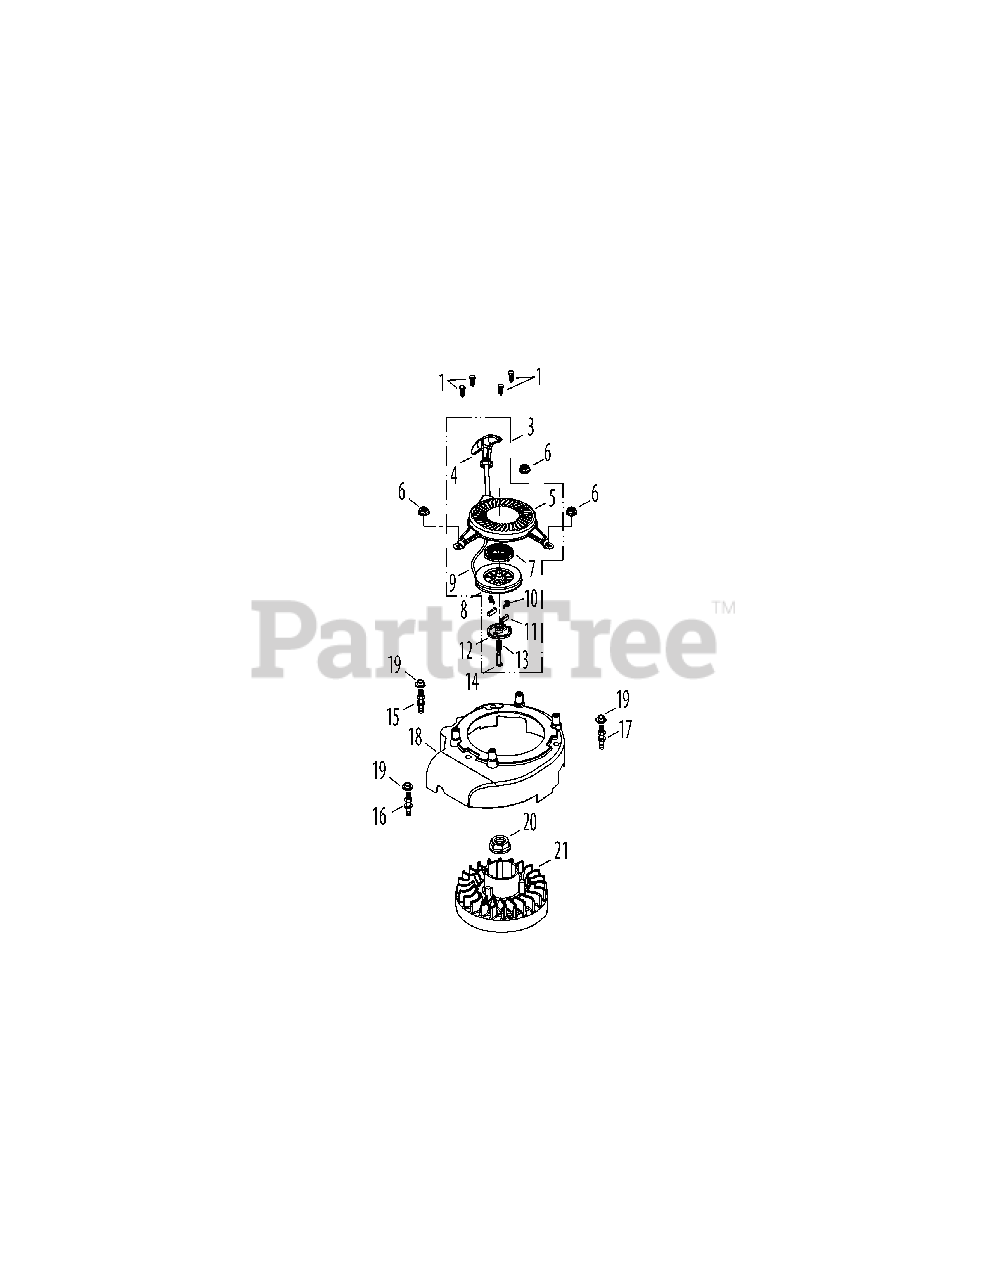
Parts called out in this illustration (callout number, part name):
1	Self-Tap Bolt, Hilo #12-16 x 1.00"
3	Recoil Starter Assembly
4	Starter Handle
5	Starter Housing
6	Nut M6 X 10 Mm
7	Recoil Spring and Pulley Assembly
8	Recoil Spring and Pulley Assembly
9	Starter Rope
10	Starter Pawl Return Spring
11	Starter Pawl
12	Pressure Plate
13	Pressure Plate Spring
14	Pressure Plate Bolt
15	Starter/Shroud Stud Black/M6 x 75
16	Starter/Shroud Stud Front/M6 x 75.3
17	Starter/Shroud Stud White/M6 x 73
18	Inner Shroud
19	Engine Shroud Spacer
20	Flywheel Nut M14
